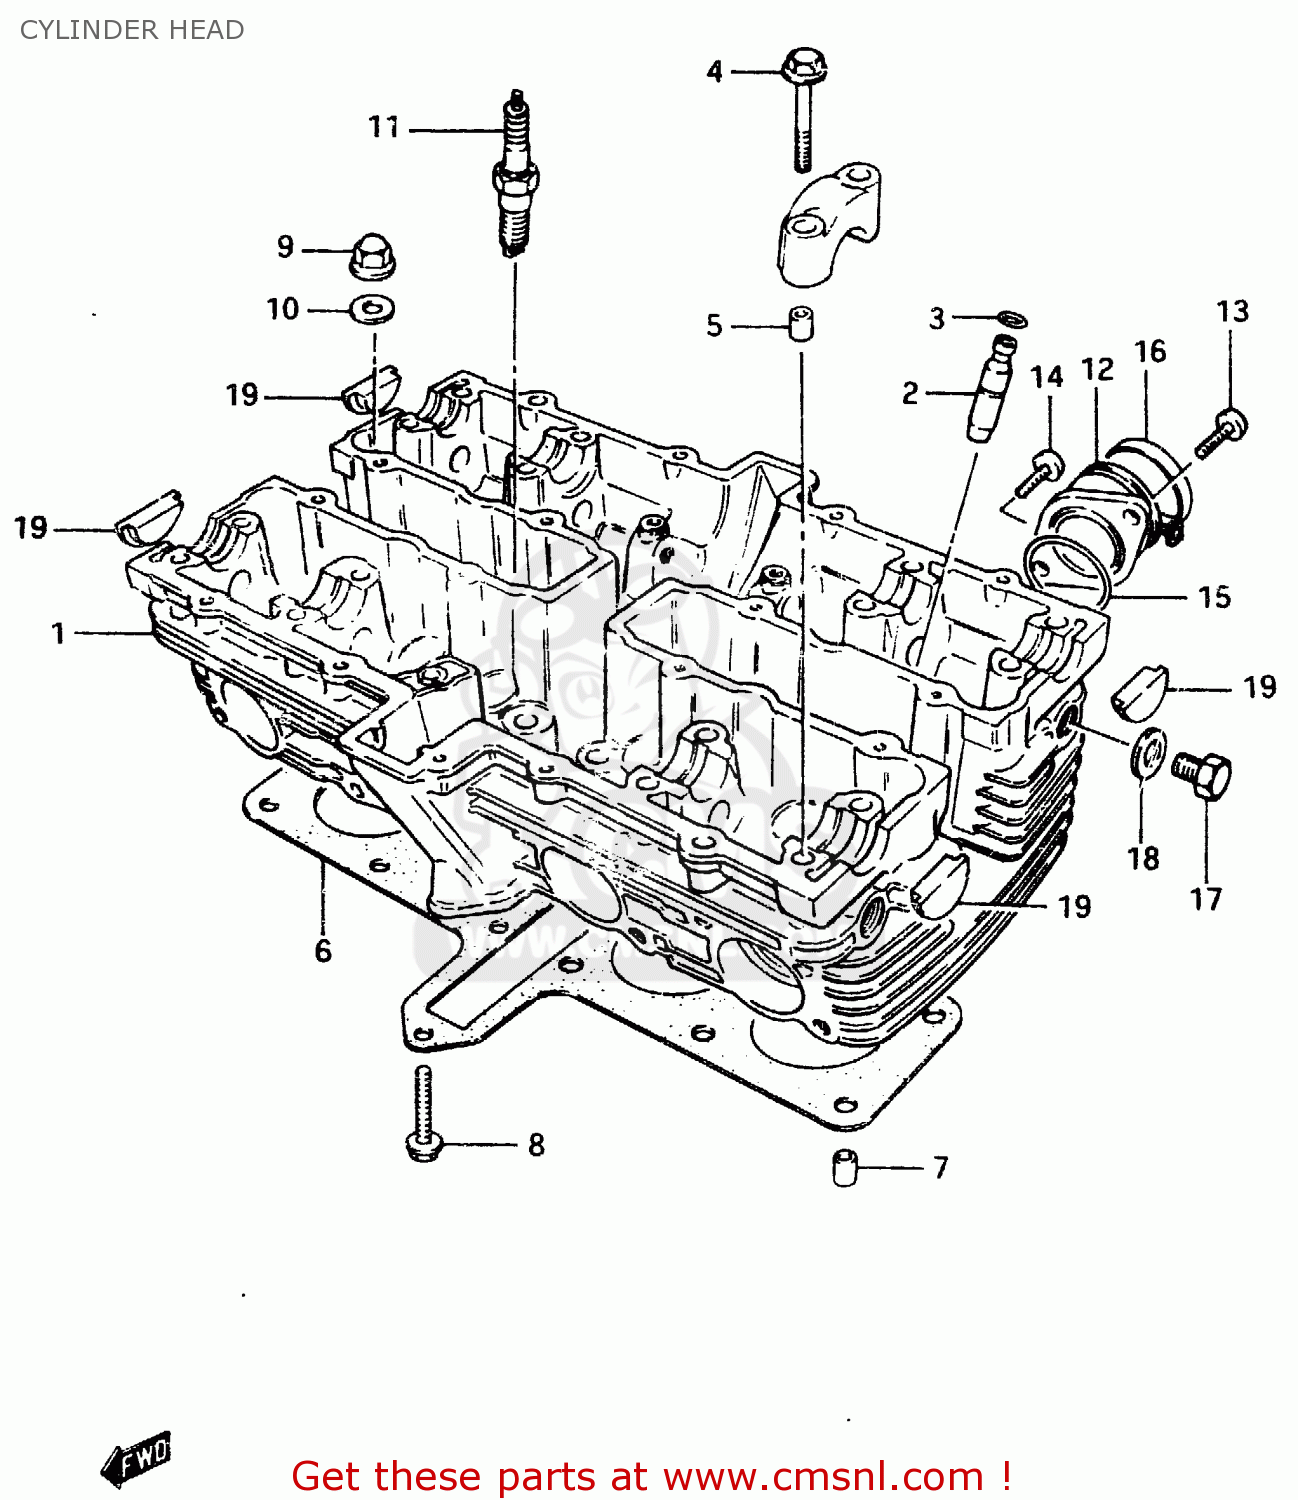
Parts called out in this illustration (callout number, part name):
1	CYLINDER HEAD SET
2	GUIDE, INTAKE VALVE
3	RING,SNAP
4	BOLT(6X39)
5	PIN(6.2X8X11)
6	GASKET,CYLINDER HEAD (NAS)
7	PIN
8	BOLT
9	NUT
10	GASKET(8.5X20X2.3) (NAS)
11	SPARK PLUG D8EA
12	PIPE, INTAKE
13	SCREW
14	SCREW
15	O RING(D:2.4,ID:31.7)
16	CLAMP
17	PLUG (14X12)
18	GASKET(14X19.2X2) (NAS)
19	PLUG
